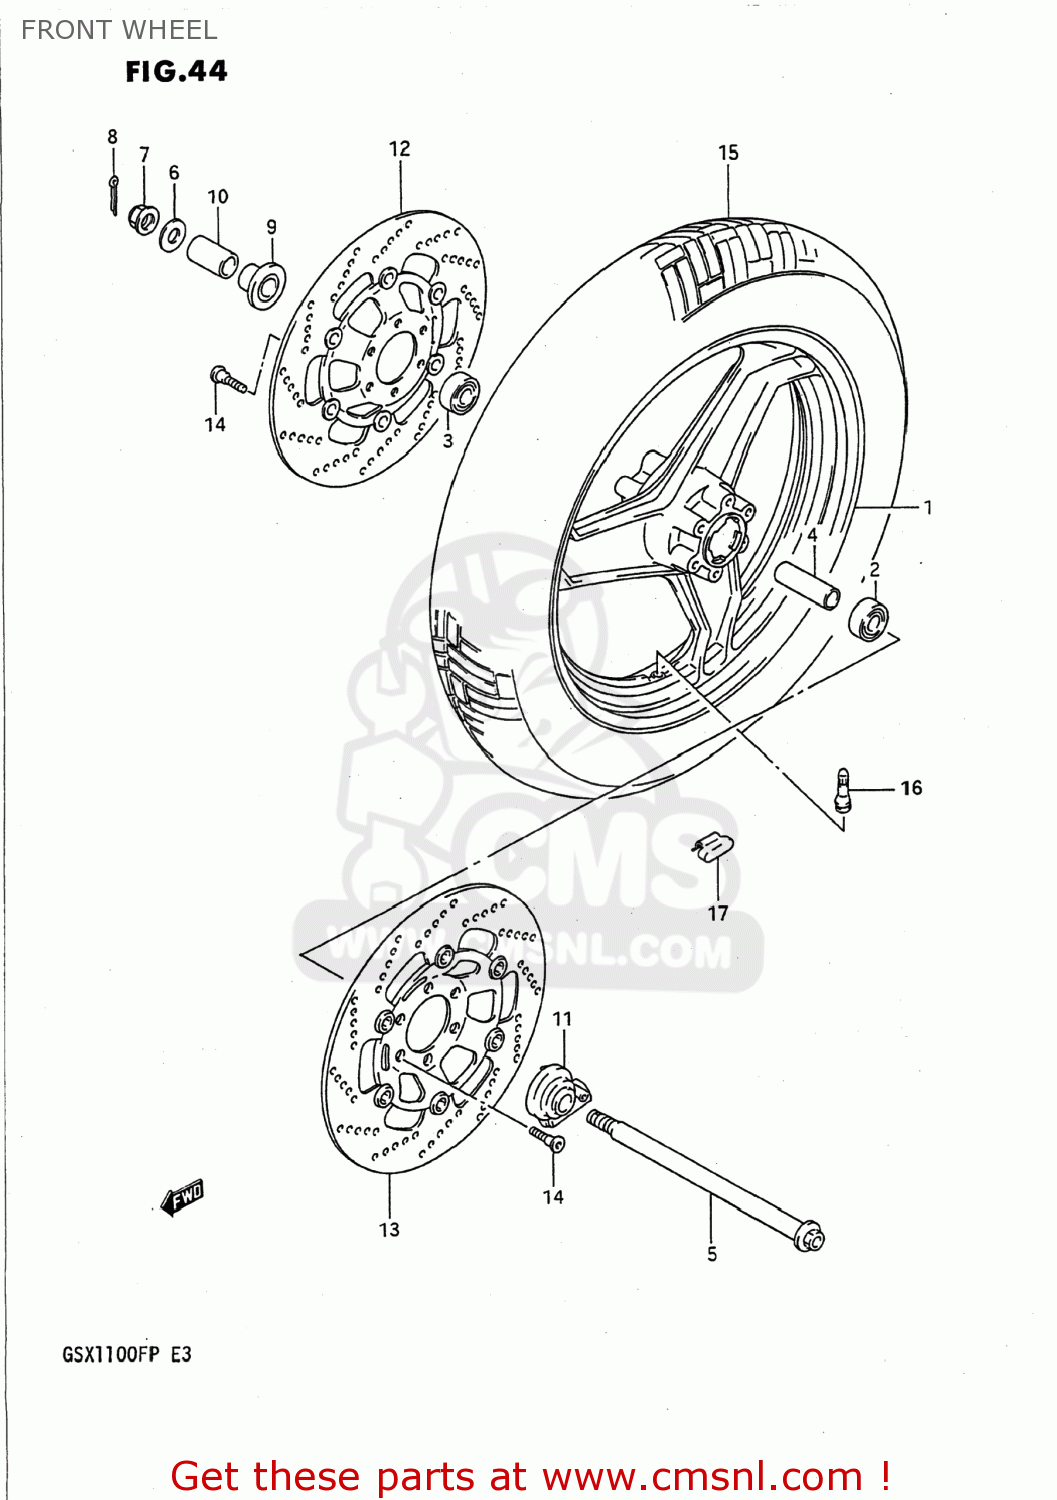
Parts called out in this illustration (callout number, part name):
1	WHEEL, FRONT (MT2.75X16) BLAC
2	BEARING(17X42X13)
3	BEARING
4	SPACER (17.3X24X78)
5	AXLE,FR
6	WASHER
7	NUT
8	COTTER PIN
9	SPACER COMP,FRONT HUB,RIGHT
10	SPACER,FRONT AXLE,RIGHT
11	BOX ASSEMBLY,SPEEDOMETER GEAR
12	DISC,BRAKE
13	DISC,BRAKE
14	BOLT
15	TIRE,FRONT
16	VALVE,TIRE
17	BALANCER,WHEEL
